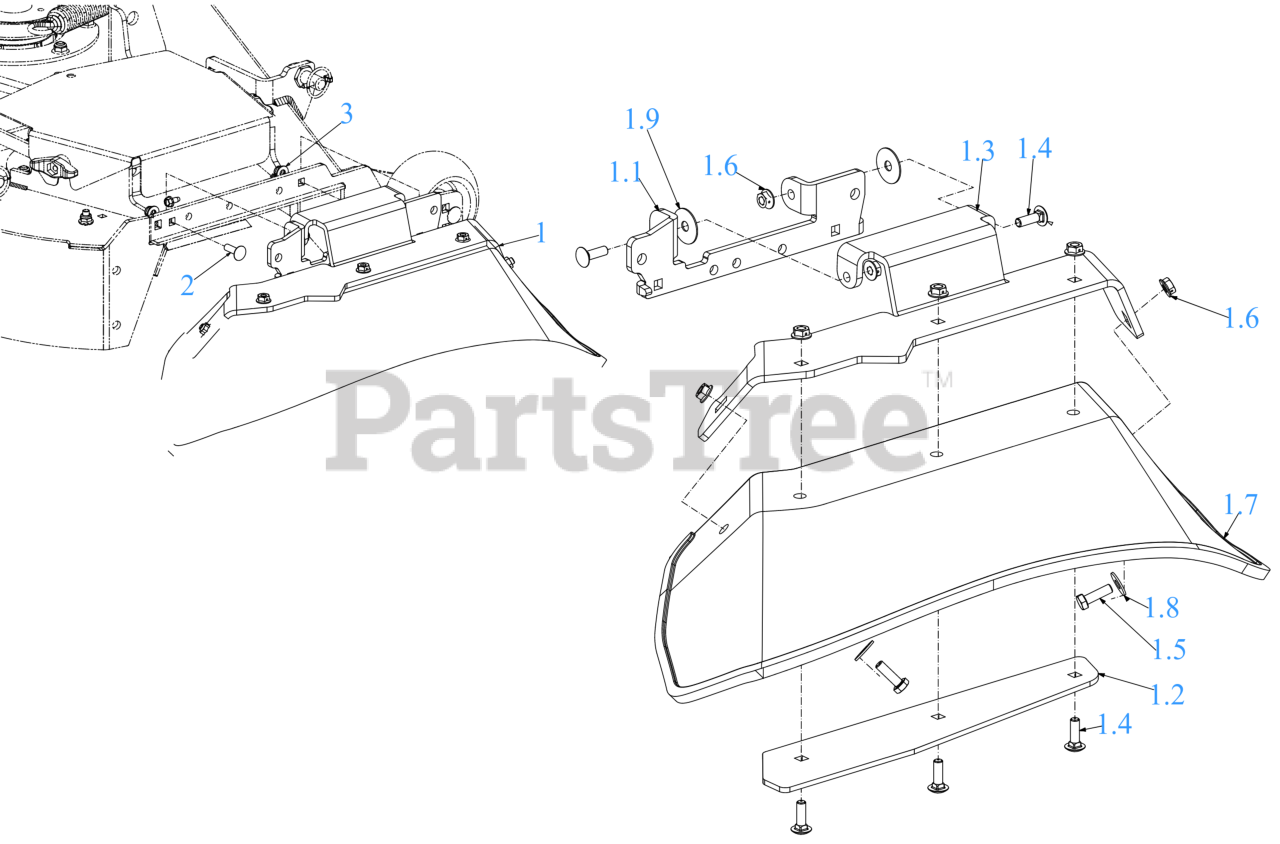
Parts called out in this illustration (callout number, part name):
1	DECK CHUTE ASSEMBLY
1.3	CHUTE BRACKET
1.4	CARRIAGE BOLT 5/16-18 x 1.00
1.5	SCREW 5/16-18 x 1.0 GR5
1.6	HEX FLANGE NUT
1.7	FIBER FORMED CHUTE
1.8	FLAT WASHER
1.9	WASHER .355X1.25X.048THK
2	CARRIAGE BOLT 5/16-18 x 1.00
3	FLANGE LOCK NUT 5/16-18
